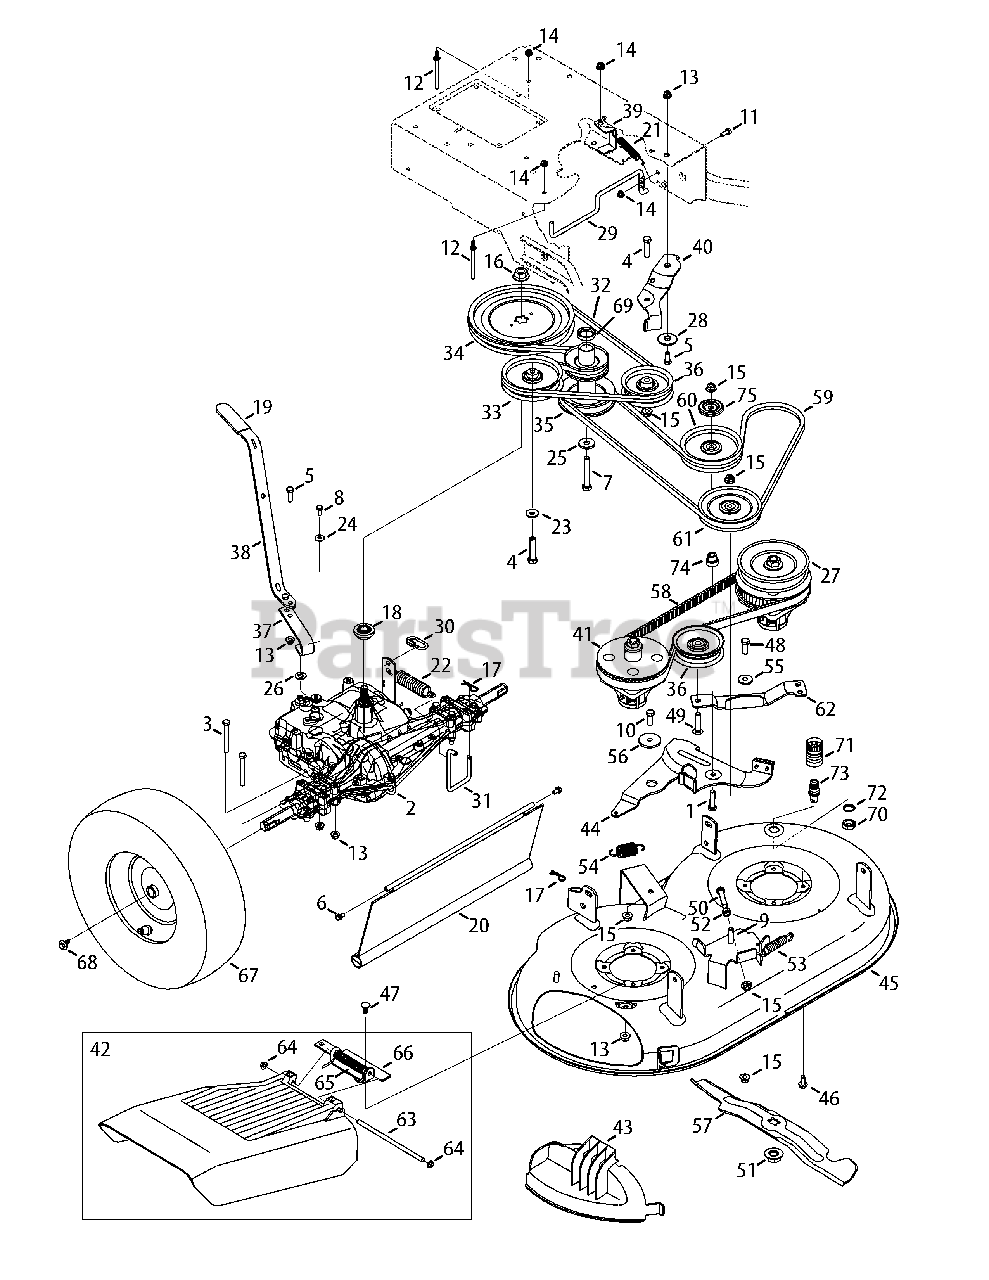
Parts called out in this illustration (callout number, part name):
1	Hex Head Cap Screw, 3/8-16 x 1.75
2	4 Speed Drive Assembly, Tecumseh
3	Hex Head Cap Screw, 5/16-18 x 2.75
4	Hex Head Cap Screw, 3/8-16 x 1.75
5	Hex Head Cap Screw, 5/16-18 x 1.00
6	Screw, 10-16 x 0.625
7	HHCS, 7/16-20 x 3.00
8	Hex Head Cap Screw, 1/4-28 x .625
9	Hex Head Cap Screw, 3/8-16 x 1.50
10	Hex Head Cap Screw, 3/8-16 x 1.25
11	Hex Head Cap Screw, 1/4-20 x .75
12	Belt Keeper, .25 DIA X 3.0
13	Flangelock Nut, 5/16-18
14	Flangelock Nut, 1/4-20
15	Flangelock Nut, 3/8-16
16	Flange Nut, 9/16-18
17	Click Pin, .092 x 1.64 LG
18	Spline Pulley Hub, 5/8
19	Grip, Black
20	Trailshield, 8.35 x 19.17
21	Extension Spring, Wheel Drive
22	Extension Spring, Brake
23	Washer, Spring, .401 x .870 x .063
24	Washer, Bell, .265 x .75 x .062
25	Washer, Flat, .450 x 1.250 x .164
26	Washer, Flat, .39 x .87 x .06
27	Drive Spindle Assembly
28	Spacer, Shoulder, .5000 x .1475
29	Belt Keeper Rod
30	Coupling Link, 3/16
31	Brake Spring Mounting Rod
32	V Belt. 4L 64.2
33	Idler Pulley, 4.25 DIA
34	Flat Sheave, DIA 7.75
35	Engine Pulley, 3.20 x 4.35 DIA
36	Idler Pulley, 3.50 DIA
37	Lower Shaft Lever
38	Upper Shaft Lever
39	Belt Keeper, .375 x 2.00
41	Spacer Spindle Assembly
42	Chute Deflector Assembly
43	Mulch Cover
44	Idler Arm Assembly
45	Deck Assembly
46	Screw, 5/16-18 x .750
47	Bolt, Carriage, 5/16-18 x .750
48	Hex Head Cap Screw, 3/8-16 x 1.00
49	Screw, Carriage, 3/8-16 x 1.75
50	Hex Head Cap Screw, 3/8-16 x 2.00
51	Flange Nut, 5/8-18
52	Hex Nut, 3/8-16
53	Extension Spring, Timing Belt
54	Extension Spring, Deck Brake
55	Shoulder Spacer, .625 ID x .169
56	Shoulder Spacer, .8840 x .190
57	2 in 1 Blade
58	Timing Belt, .315 x .787
59	Aramid V Belt, 72.2
60	Idler Pulley, 4.25" DIA
61	Idler Pulley, V-Type, 5.0 DIA
62	Timing Idler Bracket
63	Deflector Pin
64	Push Cap
65	Deflector Torsion Spring
66	Deflector Hinge Bracket
67	Wheel, 16 x 4 x 8
68	Screw, 5/16-24 x .750
69	Spacer, 1.0 x 1.28 x .31
70	Nut, Hex, M16-1.5
71	Water Nozzle Adaptor
72	Washer, Lock, 5/8
73	Deck Water Nozzle
74	Shoulder Spacer
75	Pulley Cap
